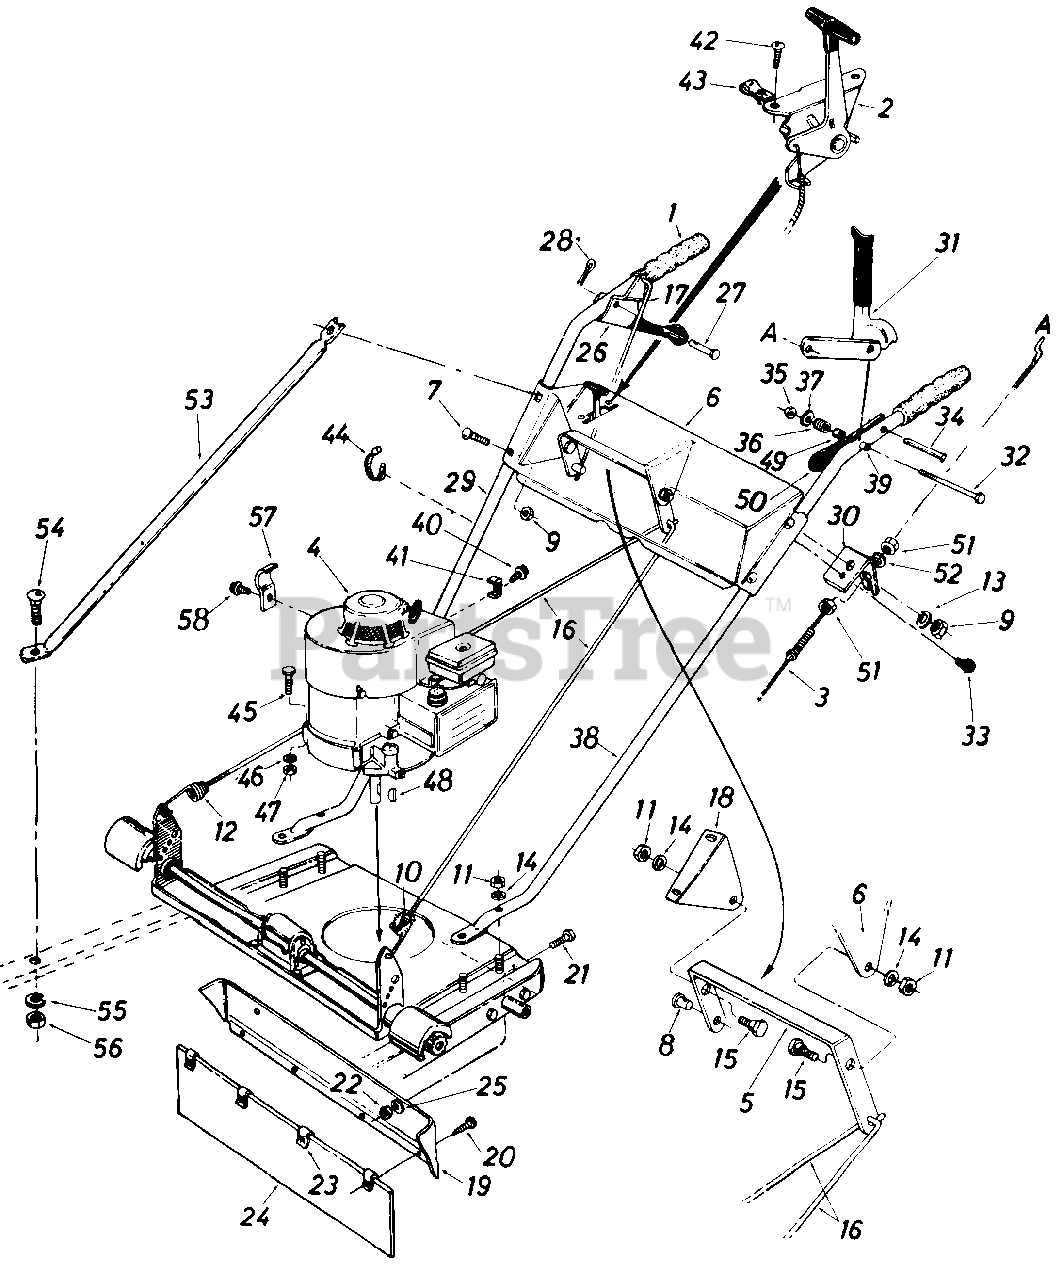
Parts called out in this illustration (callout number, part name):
1	Grip - Black
2	Throttle Control Ass'y. - Comp.
3	Clutch Cable - 56" Long
4	Engine
5	Link Bracket
6	Handle Panel Ass'y.
7	Carriage Bolt 5/16-18 x 1.75" Lg.
8	Adj. Ferrule 1/4-20 Thd.
9	Hex Nut 5/16-18 Thd.
10	Hex Ins. L-Nut 1/4-20 Thd.
11	Hex Nut 3/8-16 Thd.
12	Extension Spring
13	L-Wash. 5/16" I.D.
14	L-Wash. 3/8" I.D.
15	Shld. Bolt .500" Dia. x .295
16	Lockout Rod
17	Rod .214" Dia. x 14.87" Lg.
18	Bracket
19	Drag Shield Adapter
20	Hex B-Tap Scr. #10 x .62" Lg
21	Hex Bolt 1/4-28 x .62" Lg.
22	Hex Nut 1/4-28 Thd.
23	Speed Nut 10Z U-Type
24	Drag Shield 4.65" x 20.0" Lg.
25	L-Wash. 1/4" I.D.
26	Clutch Grip Ass'y.
27	Clevis Pin .375" Dia.
28	Intern. Cot. Pin 5/16" Dia.
29	R.H. Handle
30	Clutch Cable Brkt.
31	Blade Clutch Grip Ass'y.
32	Hex Bolt 1/4-20 x 2.25" Lg.
33	Hex Wash. S-Tap Scr. 1/4-20 x .50" Lg
35	Hex Cent. L-Nut 1/4-20 Thd.
36	Compression Spring .50" O.D. x .50" Lg.
37	Internal Tooth L-Wash.
38	L.H. Handle
39	Spacer .255" I.D.
40	Hex B-Tap Scr. #10 x .38" Lg.
41	Casing Clamp
42	Hex Wash. Hd. AB-Tap Scr. #10 x .50" Lg.
43	Speed Nut 10Z
44	Cable Tie Self Clinching
45	Hex Bolt 5/16-24 x 1.25" Lg.
46	L-Wash. 5/16" I.D.
47	Hex Nut 5/16-24 Thd.
48	#6 Hi-Pro Key 5/32 x 5/8" Dia.
49	Spacer .255" I.D. x.375" O.D.
50	Lock Spring
51	Hex Jam Nut 5/16-24 Thd.
52	L-Wash. 5/16" I.D.
54	Carriage Bolt 5/16-18 x .62" Lg.
55	L-Wash. 5/16" I.D.
56	Hex Nut 5/16-18 Thd.
57	Casing Clamp
58	Hex Wash-Hd. Tap Scr. #10 x .50" Lg.
